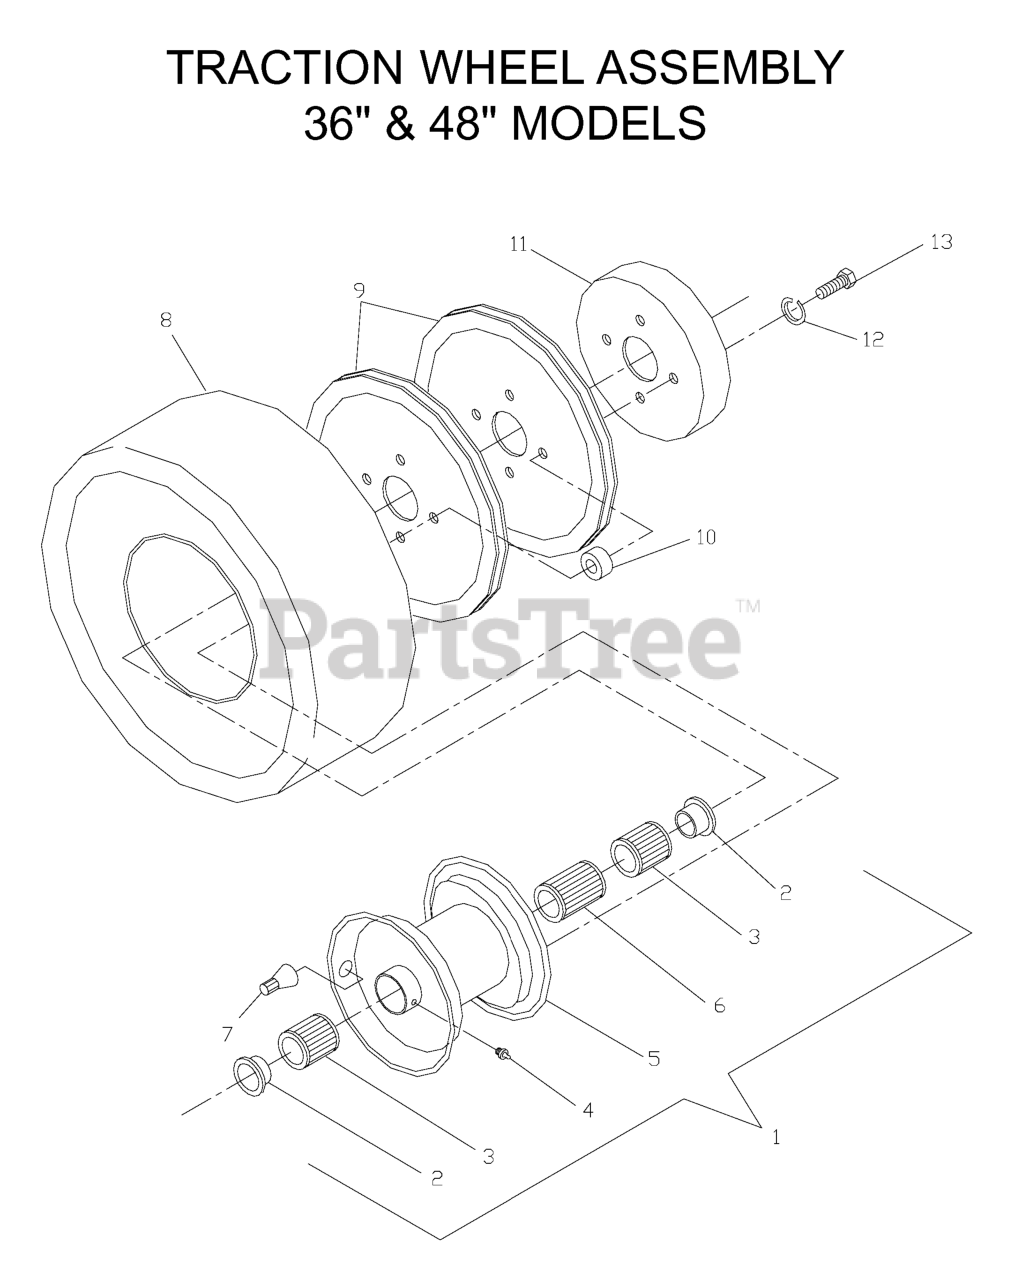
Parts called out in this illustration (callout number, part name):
1	WHEEL.ASM.13X6.5-6.SILVER.COMM
2	BEARING FLANGE
3	ROLLER BEARING (SHORT)
4	ZERK
5	RIM
6	ROLLER BEARING (LONG)
7	VALVE STEM TR-412
8	TIRE
9	TRACTION PULLEY
11	BRAKE DRUM
12	SLW 3/8 STD
13	HCS 3/8F X 1 1/2
